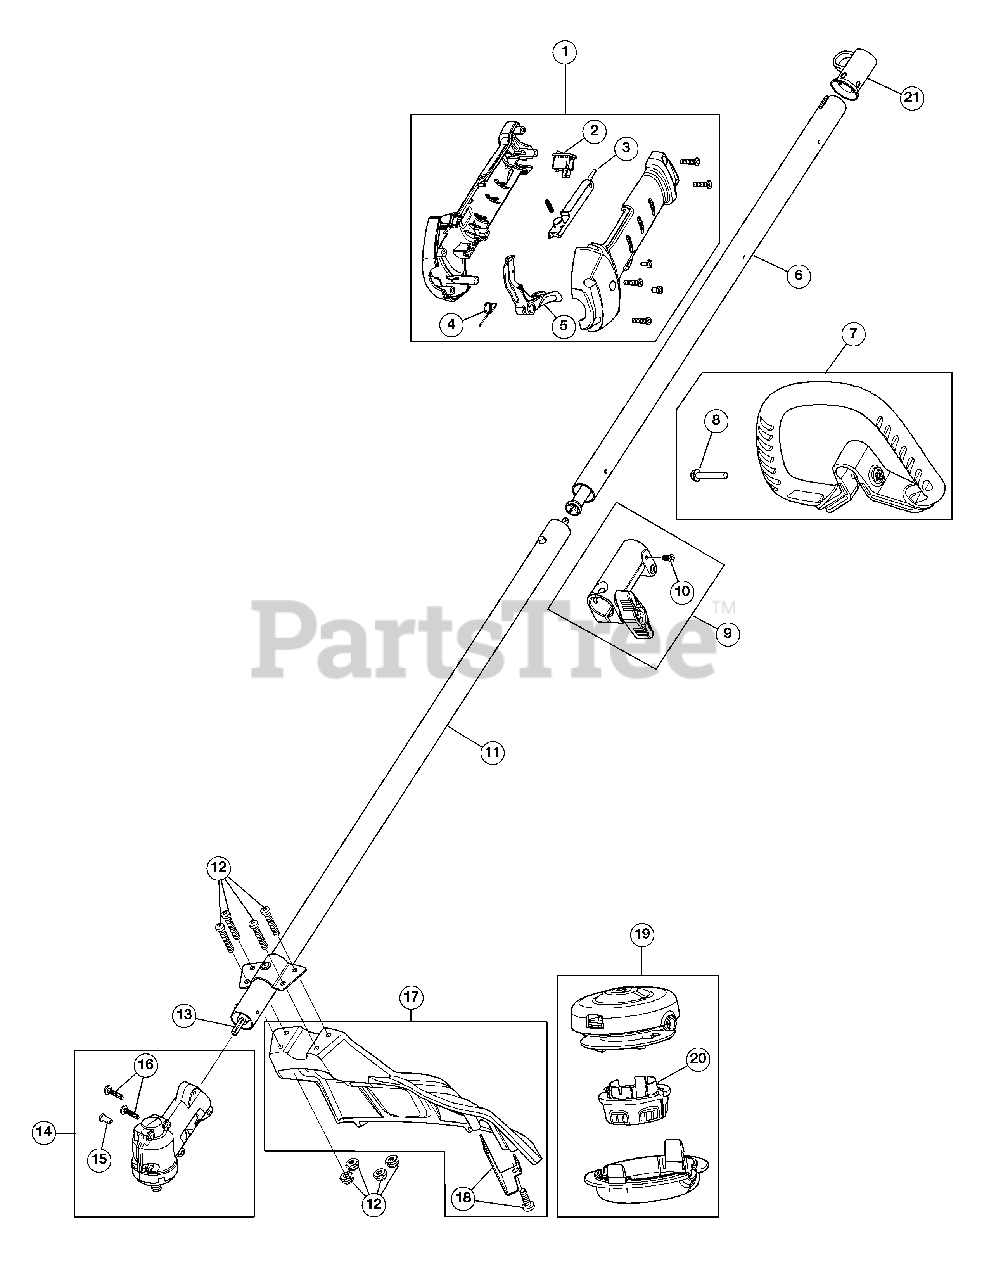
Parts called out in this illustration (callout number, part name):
1	Throttle Housing Assembly (Incl. 2 - 5)
2	Trigger Switch Assembly
3	Throttle Lock-out
4	Throttle Trigger Spring
5	Throttle Trigger
6	Upper Drive Shaft Assembly
7	D-Handle Assembly (Incl. 8)
9	Split Boom Coupler (Incl. 10)
10	Coupler Anti-Rotation Screw
11	Lower Drive Shaft Housing Assembly
12	Shield Mounting Screws and Nuts
13	Lower Flexible Drive Shaft
14	Gearbox Assembly (Incl. 15 - 16)
15	Gearbox Anti-Rotation Screw
16	Gearbox Mounting Hardware
17	Shield Assembly (Incl. 18)
18	Blade Assembly
19	Cutting Head Assembly (Incl. 20)
21	Hanger Boom End Cap
